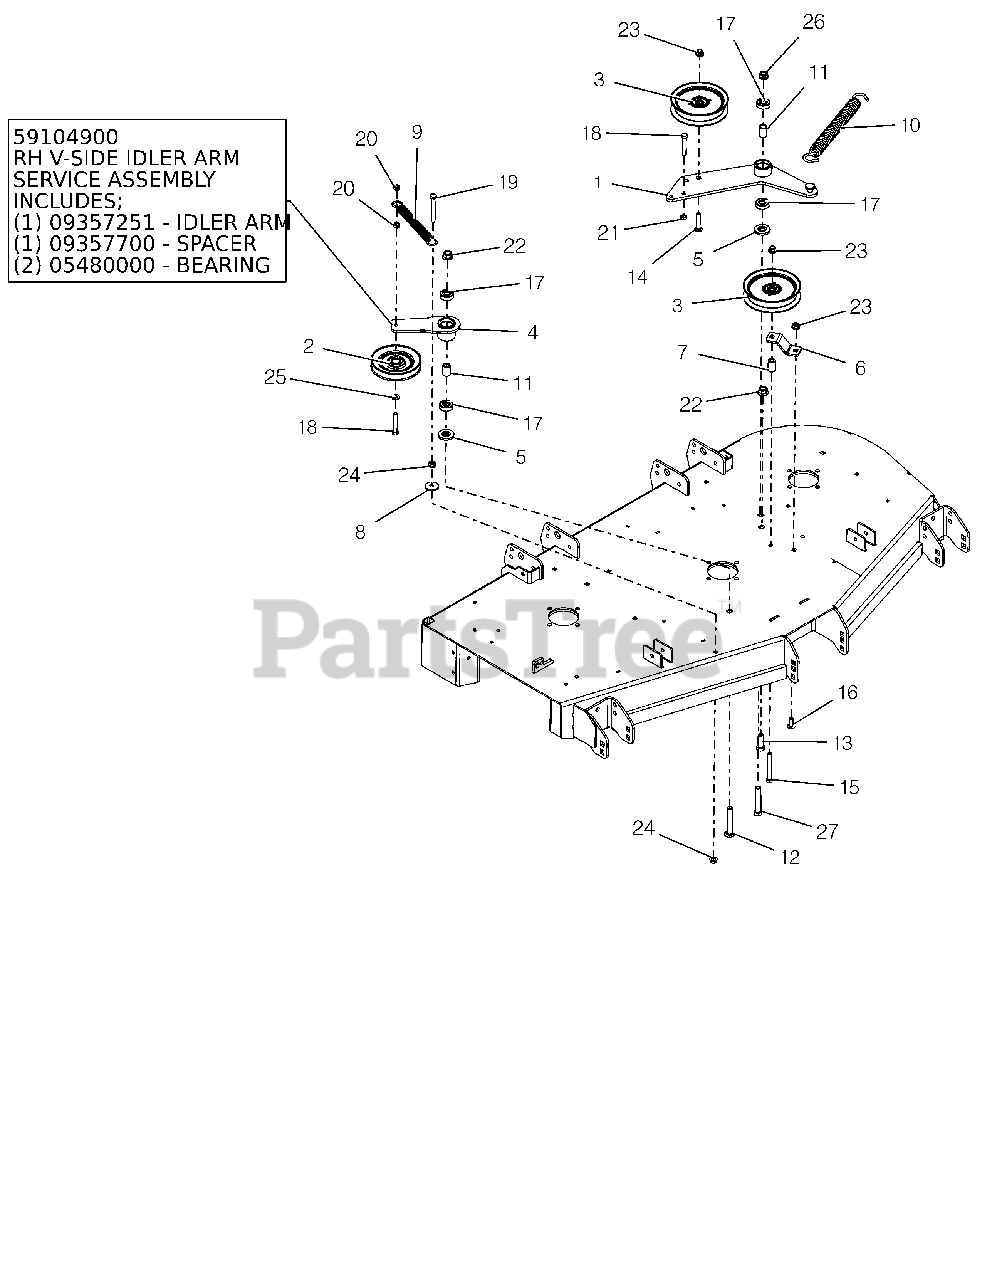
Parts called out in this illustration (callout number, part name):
1	DECK PTO IDLER ARM WLDMT - BLK
2	IDLER, V-5.00"
3	IDLER, FLAT 5.00"
4	DECK RH IDLER ARM WMT - BLK
4	RH V-SIDE IDLER ARM ASSEMBLY
4	SPACER .510 X .75 X 1.1485
4	BRG-BALL .50X1.38X.438 SEALED
5	SPACER, IDLER ARM
6	PTO FIXED IDLER MTG BRKT -RED
7	BUSHING, SLV .380X.750X1.190
8	WSHR-FL-STL .406X1.375X.135 YZ
9	SPRING, EXTENSION
10	SPRING, EXTENSION
11	SPACER .510 X .75 X 1.1485
12	BLT,RDHDSQSHNK.50-13X3.25 G5YZ
13	@BLT-HEX .50-13X1.50 GR5 YWZC
14	BLT-RDHDSQNK .38-16X2.00 SHTYW
15	@BLT-HEX .38-16X3.25 GR5 YWZC
16	@BLT-RDHDSHSQNK.38-16X1.0 G5YZ
17	BRG-BALL .500X1.38X.437
18	@BLT-HEX .38-16X2.25 GR5 YWZC
19	@BLT-HEX .38-16X3.00 GR5 YWZC
20	@NUT-LK-CTR .38-16 YWZC
21	NUT-HEX-JAM .375-16 YWZC
22	@NUT-LK-NYL-FLG .50-13 YWZC
23	@NUT-LK-NYL-FLG .38-16 YWZC
24	@NUT-SPNLK-FLG .375-16 YWZC
25	@WSHR-FL-STL.406X.812X.065 YWZ
26	NUT-LK-CTR-FLG .50-13 YWZC
27	@BLT-HEX .50-13X3.00 GR5 YWZC
